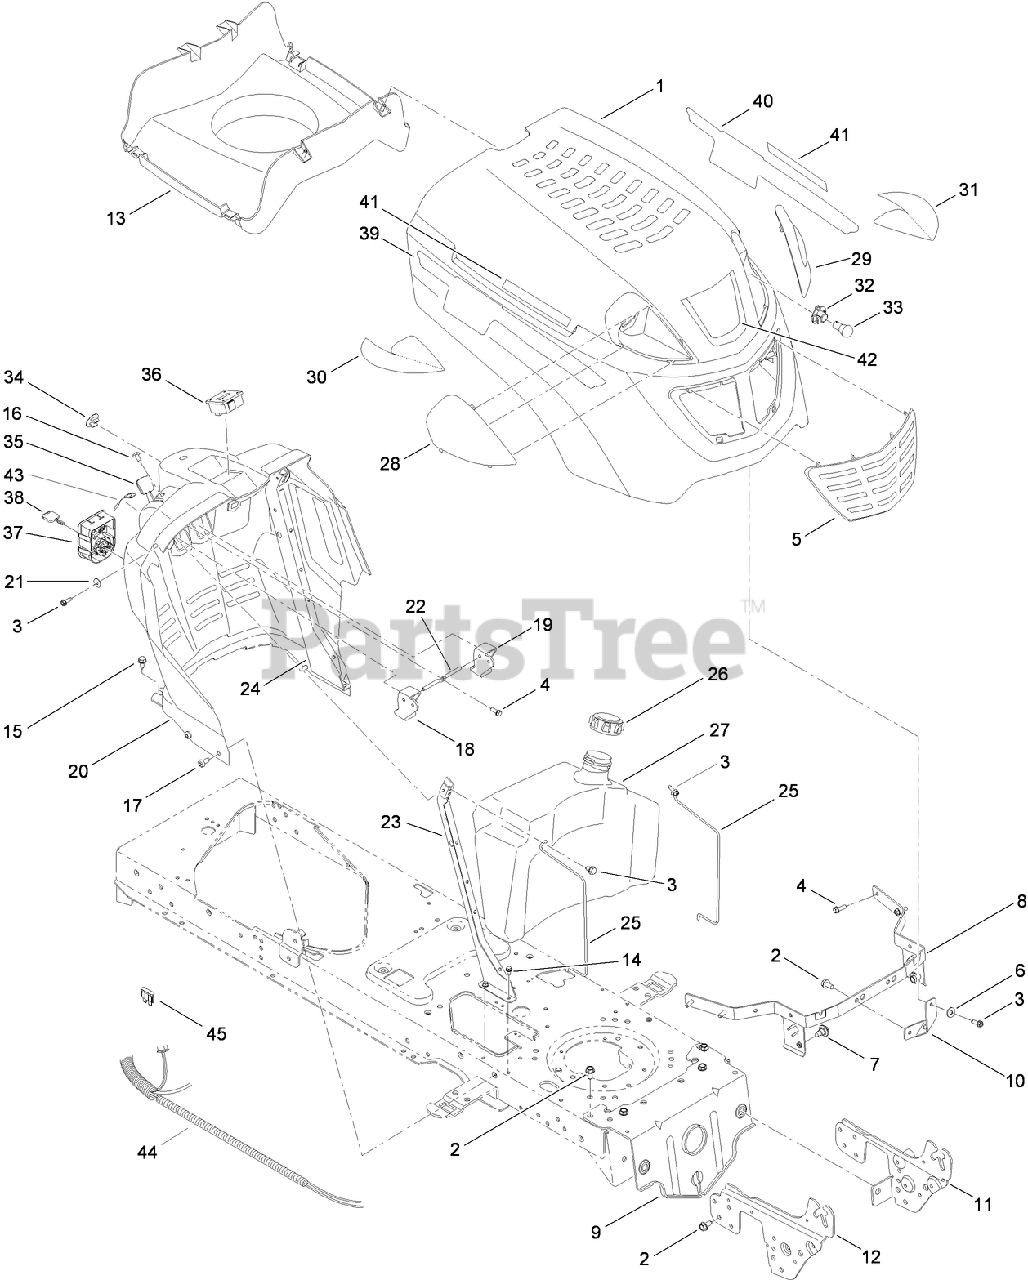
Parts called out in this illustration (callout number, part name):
2	SCREW-TAP
3	SCREW-TAP
4	SCREW-TAP
6	WASHER-FLAT
7	BOLT-SHOULDER, TAP
8	BRACKET-PIVOT
9	BRACKET-PIVOT
10	BRACKET-SUPPORT, HOOD
11	BRACKET-SUPPORT, PIVOT (LH)
12	BRACKET-SUPPORT, PIVOT (RH)
13	PLENIUM-HOOD
14	SCREW-HWHTF
15	SCREW-TAP
16	SCREW-TAP
17	SCREW-TAP
18	LEVER-CRUISE
19	LEVER-BRAKE
20	DASH-MANUAL, PTO
21	WASHER-SPRING
22	ROD-LEVER, BENT
23	SUPPORT-DASH, PLATE (RH)
24	SUPPORT-DASH, PLATE (LH)
25	ROD-SUPPORT
26	CAP-FUEL
27	TANK-FUEL, 3 GAL
28	LENS-RH
29	LENS-LH
30	REFLECTOR-RH
31	REFLECTOR-LH
32	SOCKET-HEADLIGHT
33	LAMP-12V, MINIATURE
34	PLUG-CHOKE
35	CABLE-THROTTLE/CHOKE
36	METER-HOUR
37	MODULE-SWITCH, IGNITION
38	KEY-IGNITION
39	DECAL-HOOD, RIGHT SIDE
40	DECAL-HOOD, LEFT SIDE
42	DECAL-HOOD
43	DECAL-THROTTLE
44	HARNESS-WIRING
45	FUSE-20 AMP
